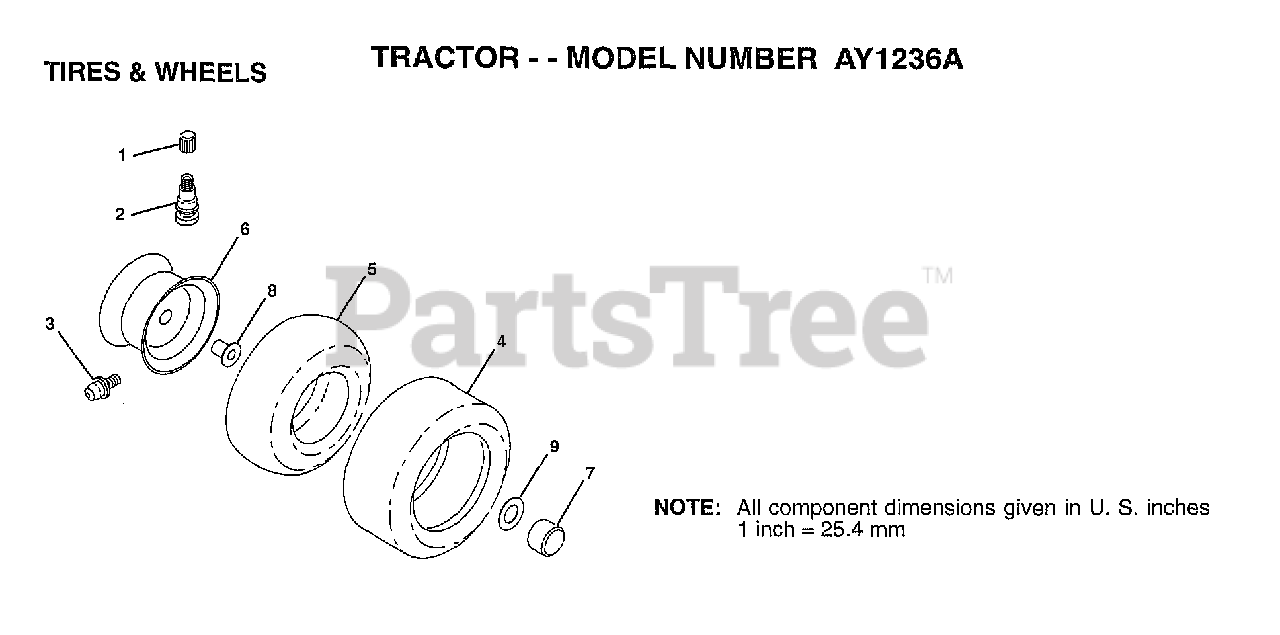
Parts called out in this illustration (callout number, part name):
1	VALVE CAP
2	VALVE STEM LT
3	FITTING LT
5	TUBE.5.3/4.5/6
5	TUBE.16X6.5/7.5-8
6	"RIM FRONT 6"""
6	"RIM ASM REAR 8"""
7	HUB CAP
8	"FLANGE, BEARING"
9	WASHER
